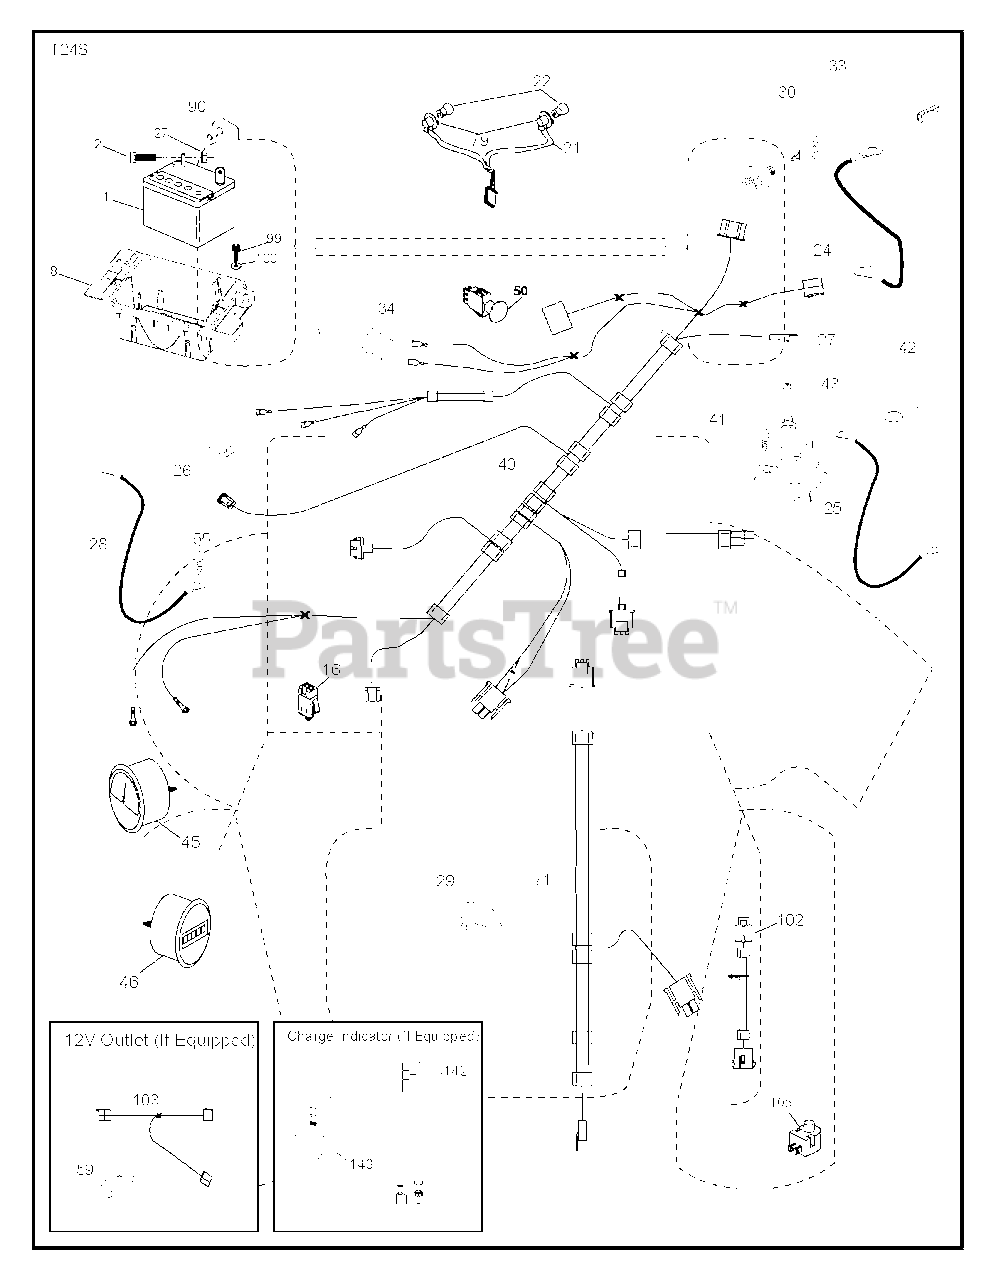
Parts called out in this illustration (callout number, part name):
1	Battery, Dry 30 Amp
2	BOLT.HEX.1/4.X.3/4.DICHROMATE
8	TRAY.BATTERY BOX.FRONT
16	SWITCH INTERLOOK PUSH-IN
21	HARNESS.LIGHT W/4152J BULBS
24	CABLE.FRBATT.W/WIRE.8GA.8
25	CABLE.STARTER.8GA.17.5
26	FUSE 20AMP
27	NUT
28	CABLE.GROUND.21"BLK.8GA.90T
29	SWITCH.SEAT.DELTA.OPC.
30	SWITCH.IGN.DELTA.W.LGH.ROS
33	KEY.CHAIN.BLISTER.PACK.GEN.USA
40	HARNESS.IGN.DSH.W112V.WPORTWIR
41	SCREW
42	TERMINAL COVER
43	SOLENOID.W/BRASS.PLUNGER
45	GAUGE.AMMETER.SILVER/WHITE
46	GAUGE.HOUR.METER.SILVER/WHITE
50	RP SWTICH.PTO.8.TERMINAL
55	SCREW 5/16"
71	HARNESS-CHASSIS SUB
79	BULB HOLDER ASM.
90	COVER.TERMINAL.BATTERY
99	SCREW HEXWSHR 1/4-20X3/4
102	HARNESS PIGTAIL PCH TEX ROS
105	REVERSE SWITCH
